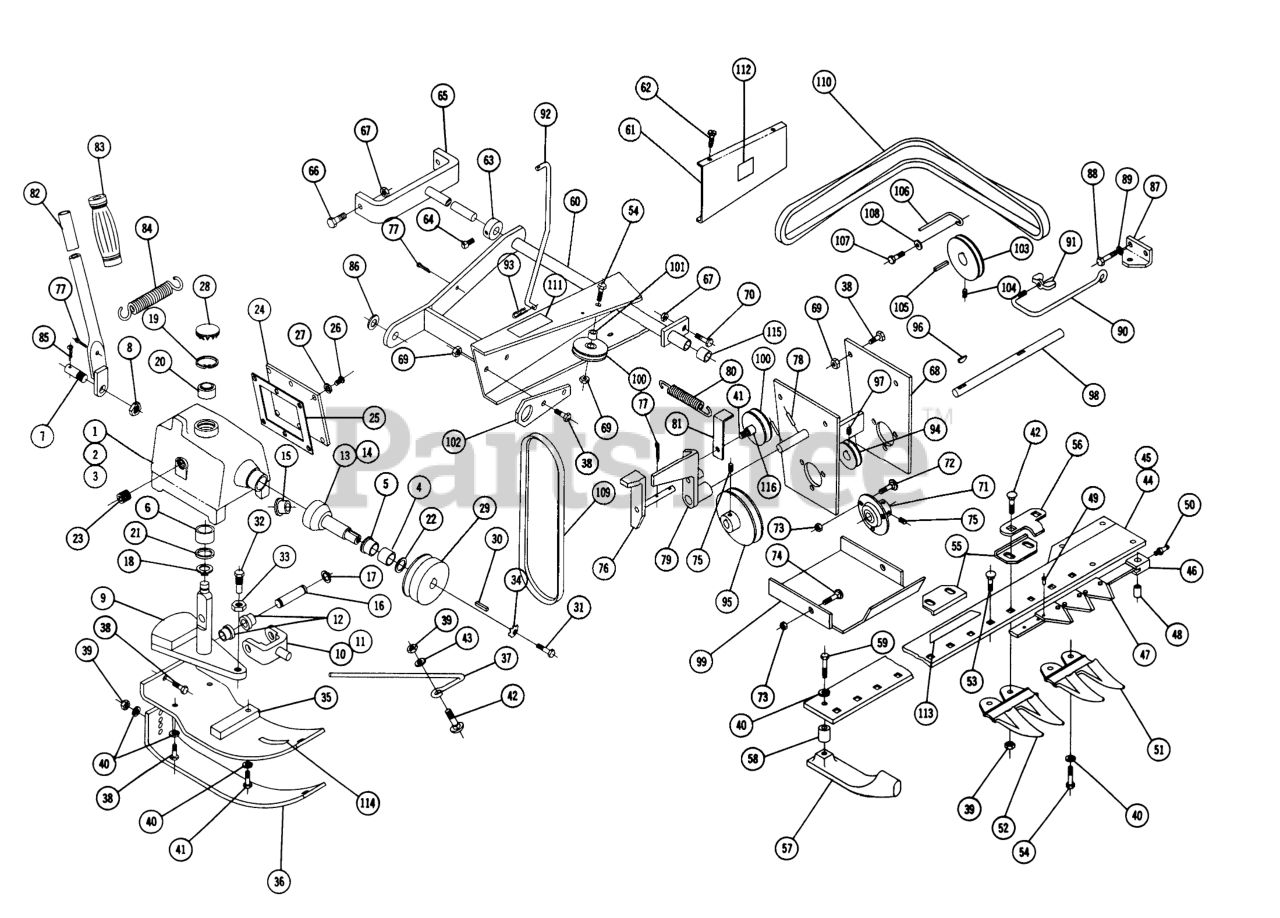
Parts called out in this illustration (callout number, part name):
1	Ass-y Housing Complete-Sickle Drive
2	Ass-y Housings & Bearings
3	Housing
4	Bearing-Bronze Sleeve
5	Bearing-Bronze Sleeve
6	Bearing-Bronze Sleeve
7	Pin
8	Nut, 3/4-16
9	Ass-y. Shaft-Weldment
10	Ass-y. Yoke
11	Yoke
12	Bearing-Bronze Sleeve
13	Ass-y. Shaft & Bearing
14	Shaft
15	Bearing-Bronze Sleeve
16	Pin Yoke
17	SNAP RING- 5/8 EXT
18	SNAP RING
19	Ring-Snap
20	Bearing-Ball
21	Seal 1 1/4 I.D.
22	Seal
23	Plug-Pipe 1"
24	Cover Plate
25	Gasket
26	Screw-Rd. Hd. #10-24 x 3/8
27	Lockwasher #10
28	Plug Button
29	Pulley 4 Dia.
30	KEY-STRAIGHT
31	Bolt 3/8-16 x 7/8
32	Pin Sickle Drive
33	Nut-5/8-18
34	WASHER
35	Ass y. Shoe-Upper-Weldment
36	Shoe-Lower
37	Rod-Grass
38	Bolt 3/8-16 x 1
40	Lockwasher
41	Bolt, 3/8-16 x 1/2
42	Bolt Carriage 3/8-16 x 1
43	Washer Dia. U.S.
44	Ass-y. Cutter Bar Complete
45	Ass-y. Bar Guard
46	Ass-y. Knife Bar & Sections
47	Section
48	Bushing
49	Rivet
50	ZERK 90DEGREE
51	Twin Guard
52	Guard Cutter Bar
53	Bolt Carriage 3/8-16 x 1
54	Bolt Hex 3/8-16 x 1 1/4
55	Wear Plates
56	Clip, Hold Down
57	Skid
58	Spacer
59	Bolt, 3/8 16 x 2
60	Ass-y Frame
61	Cover Belt
62	Screw Hex Self Tap #8-32 x 3/8
63	Collar
64	Screw-Set
65	Ass-y. Bracket & Rod
66	Bolt Hex 1/2-13 x 1 1/4
67	Locknut-1/2-13
68	Ass-y. Shaft Support
69	3/8-16 E.S.
70	Bolt 1/2-13 x 3 Square Hd.
71	Bearing-Flanged
72	Bolt Hex 5/16-18 x 3/4
73	Nut-Nylok
74	Bolt-Car. 5/16-18 x 1
75	Set Screw 5/16-18 x 5/16
76	Ass-y. Lever
77	Cotter Pin
78	Roll Pin
79	Pedal
80	SPRING R
81	BRACKET GUARD
82	Ass-y Lever Lift
83	Grip
84	Spring
85	Cotter Pin 3/16 x 1
86	Washer
87	Bracket-Travel Hook
88	Bolt 5/16-18 x
89	Lockwasher
90	Hook-Travel Support
91	3/8 NC Wing Nut
92	Lift Rod
93	Hairpin
94	Pulley
95	Pulley
96	Key
97	Set Screw 1/4-20
98	Shaft
99	Shield Pulley
100	Pulley
101	SPACER
102	Link
103	Puller-Engine-Drive
104	Set Screw 1/4-20 x 5/16 Hex
105	Key
106	RETAINER BELT
107	Bolt Hex 5/16-18
108	Washer
109	Belt-Engine Drive
110	V BELT
111	Decal-Caution
112	Decal
113	Decal
114	Decal
115	Bushing
116	Spacer
